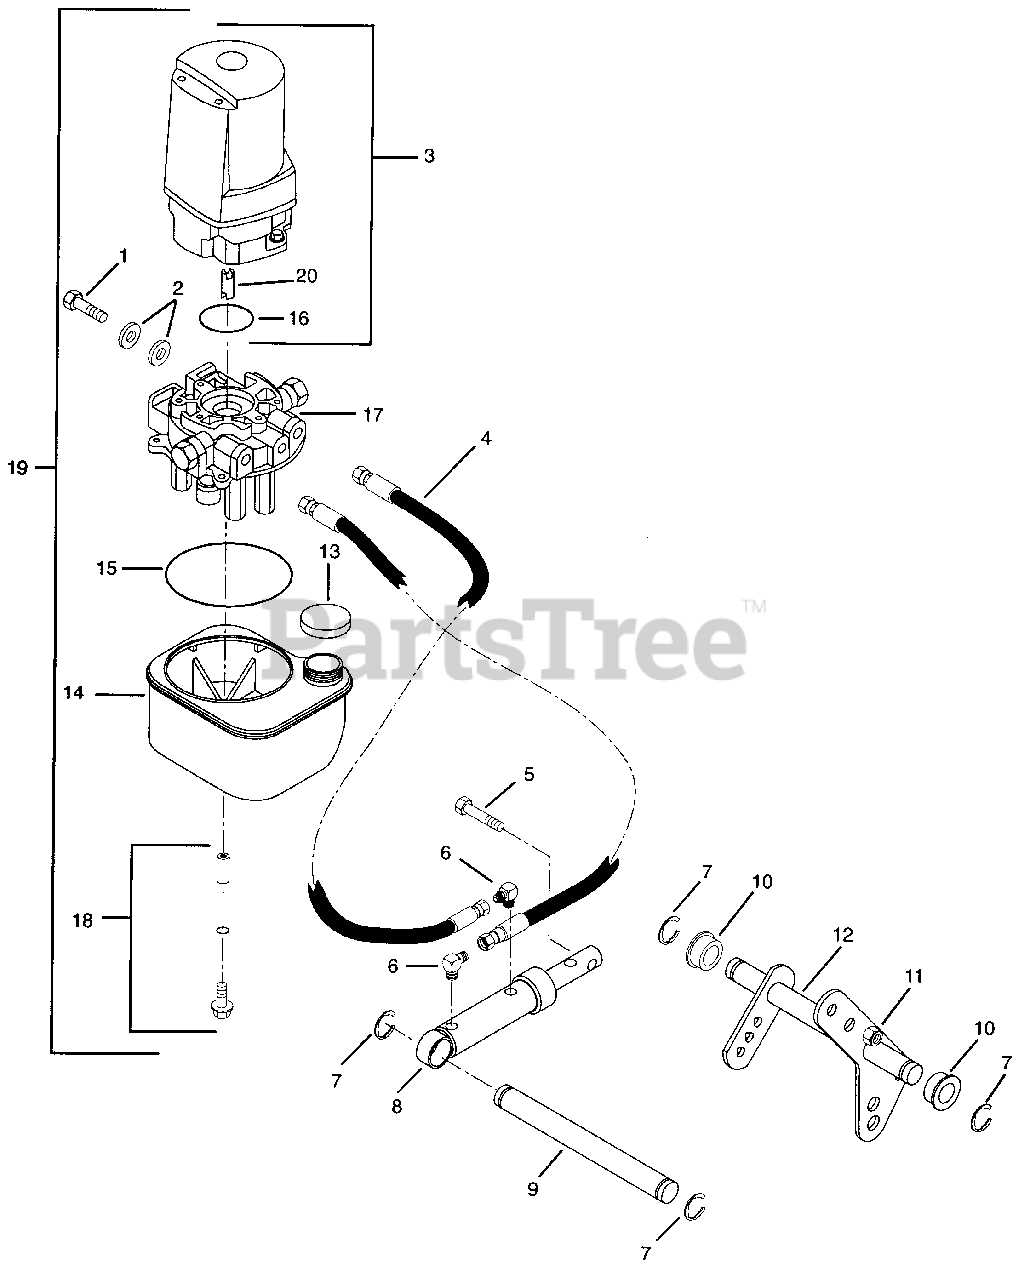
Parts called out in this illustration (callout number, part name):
1	Bolt-Hex .38-16 x 1.00
2	Washer-Flat-Steel .390 x .875 x .18
3	Motor Assembly
4	Assembly-Hose Pump to Cylinder
5	Bolt-Hex .50-13 x 2.00 Grade 5
6	Adapter 2503-4-4
7	Ring-Retaining-External .835 x .056
8	Cylinder-Hydraulic
9	Shaft-Hydraulic Cylinder
10	Bushing-Flange 1.020 x 1.385 x .75 x 1.75
11	Nut-Locking-Center .50-13
12	Mower Lift Weldment
13	Reservoir Cap-Electric Hydraulic Pump
14	Reservoir Tank
15	Reservoir Seal O-Ring
17	Adapter Assembly
18	Screw O-Ring and Spacer Assembly
19	Pump-Electric Hydraulic
